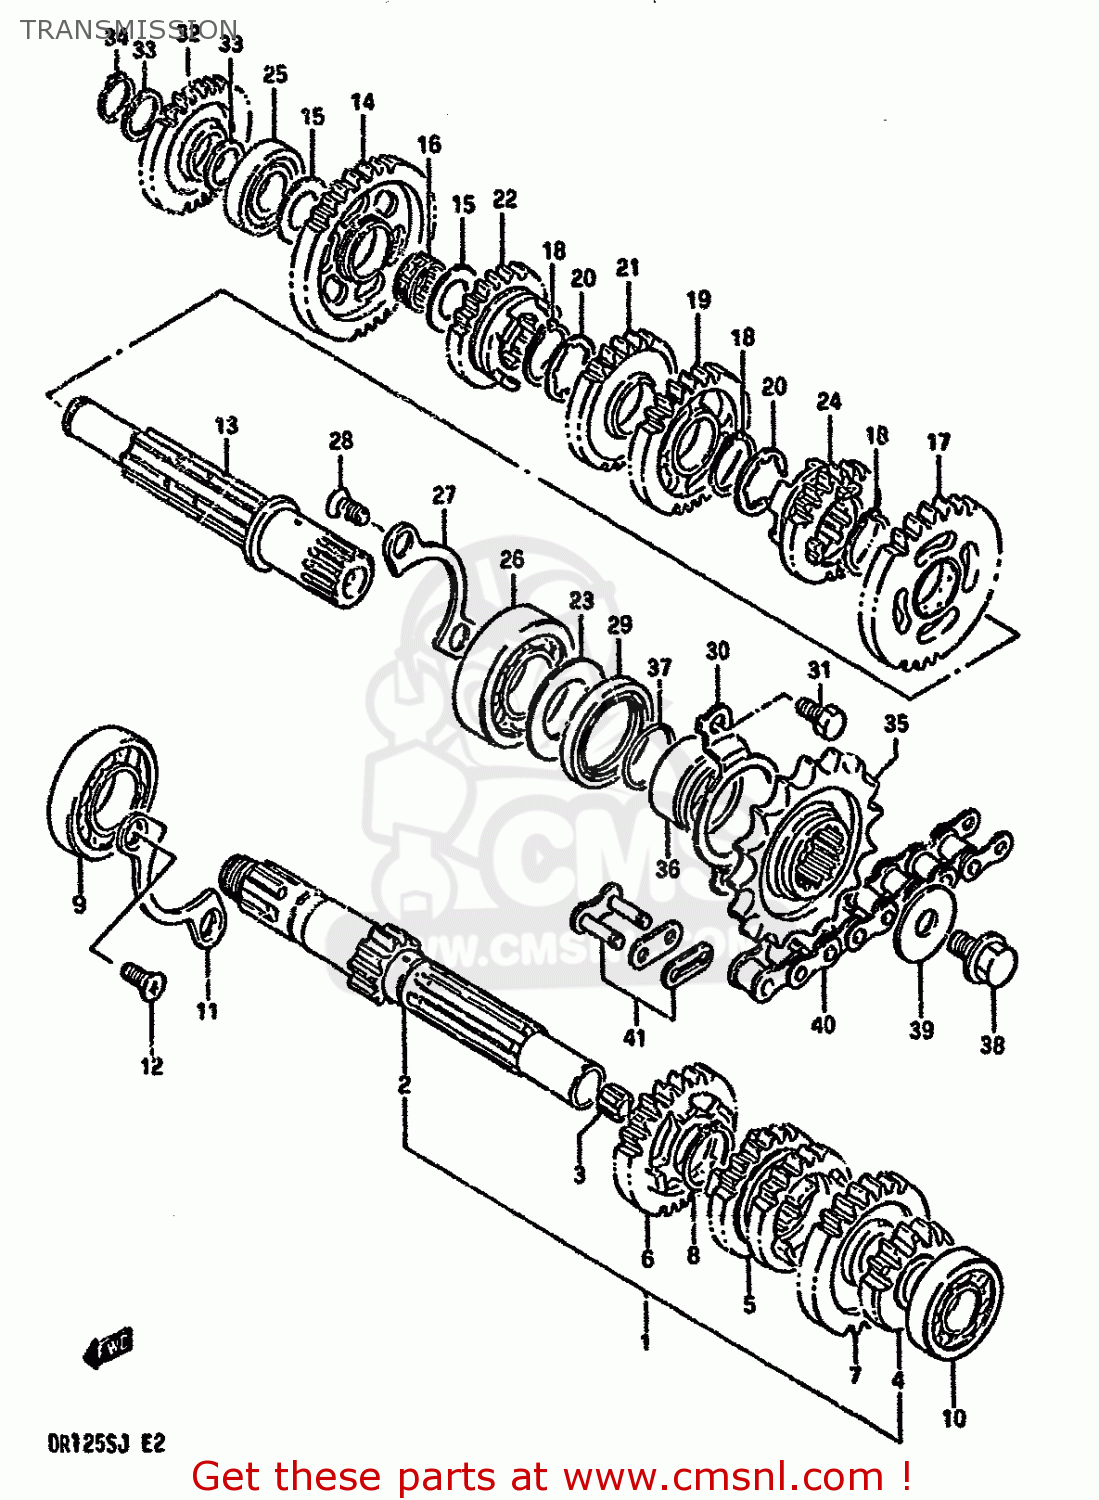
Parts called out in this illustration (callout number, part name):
1	SHAFT ASSEMBLY,COUNTER
2	SHAFT,COUNTER
3	BUSH
4	GEAR,SECOND DRIVE
5	GEAR,THIRD & FOURTH DRIVE,N
6	GEAR,FIFTH DRIVE
7	GEAR,SIXTH DRIVE
8	CIRCLIP
9	BEARING
10	BEARING, LH
11	RETAINER,DRIVE SHAFT BEARING
12	SCREW
13	SHAFT,DRIVE
14	GEAR,FIRST DRIVEN
15	WASHER
16	BEARING(15X19X7.8)
17	GEAR,SECOND DRIVEN
18	CIRCLIP
19	GEAR,THIRD DRIVEN
20	WASHER,LOCK
21	GEAR,FOURTH DRIVEN
22	GEAR,FIFTH DRIVEN
23	WASHER,OIL SEALING
24	GEAR,SIXTH DRIVEN
25	BEARING(15X36X12)
26	BEARING(22X50X14)
27	RETAINER,DRIVE SHAFT BEARING
28	SCREW
29	SEAL,OIL(30X40X6)
30	RETAINER,DRIVESHAFT O
31	BOLT
32	GEAR,KICK STARTER IDLE(NT:26)
33	WASHER
34	CIRCLIP,15MM
35	SPROCKET,ENGINE
36	SPACER,ENGINE SPROCKET
37	O RING(D:2.5,ID:21)
38	BOLT
39	WASHER
40	CHAIN ASSEMBLY,DRIVE
41	JOINT SET,CHAIN
